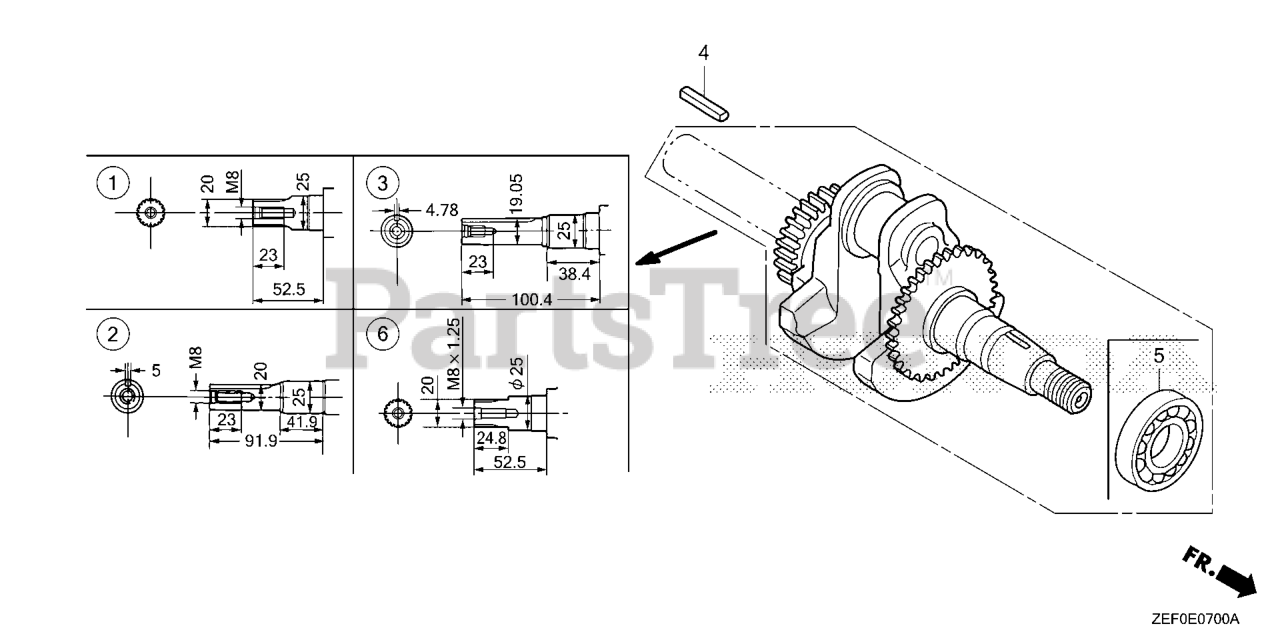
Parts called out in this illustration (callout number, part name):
3	CRANKSHAFT
5	BEARING, RADIAL BALL (6205)
5	BEARING, RADIAL BALL (6205) (NSK)
